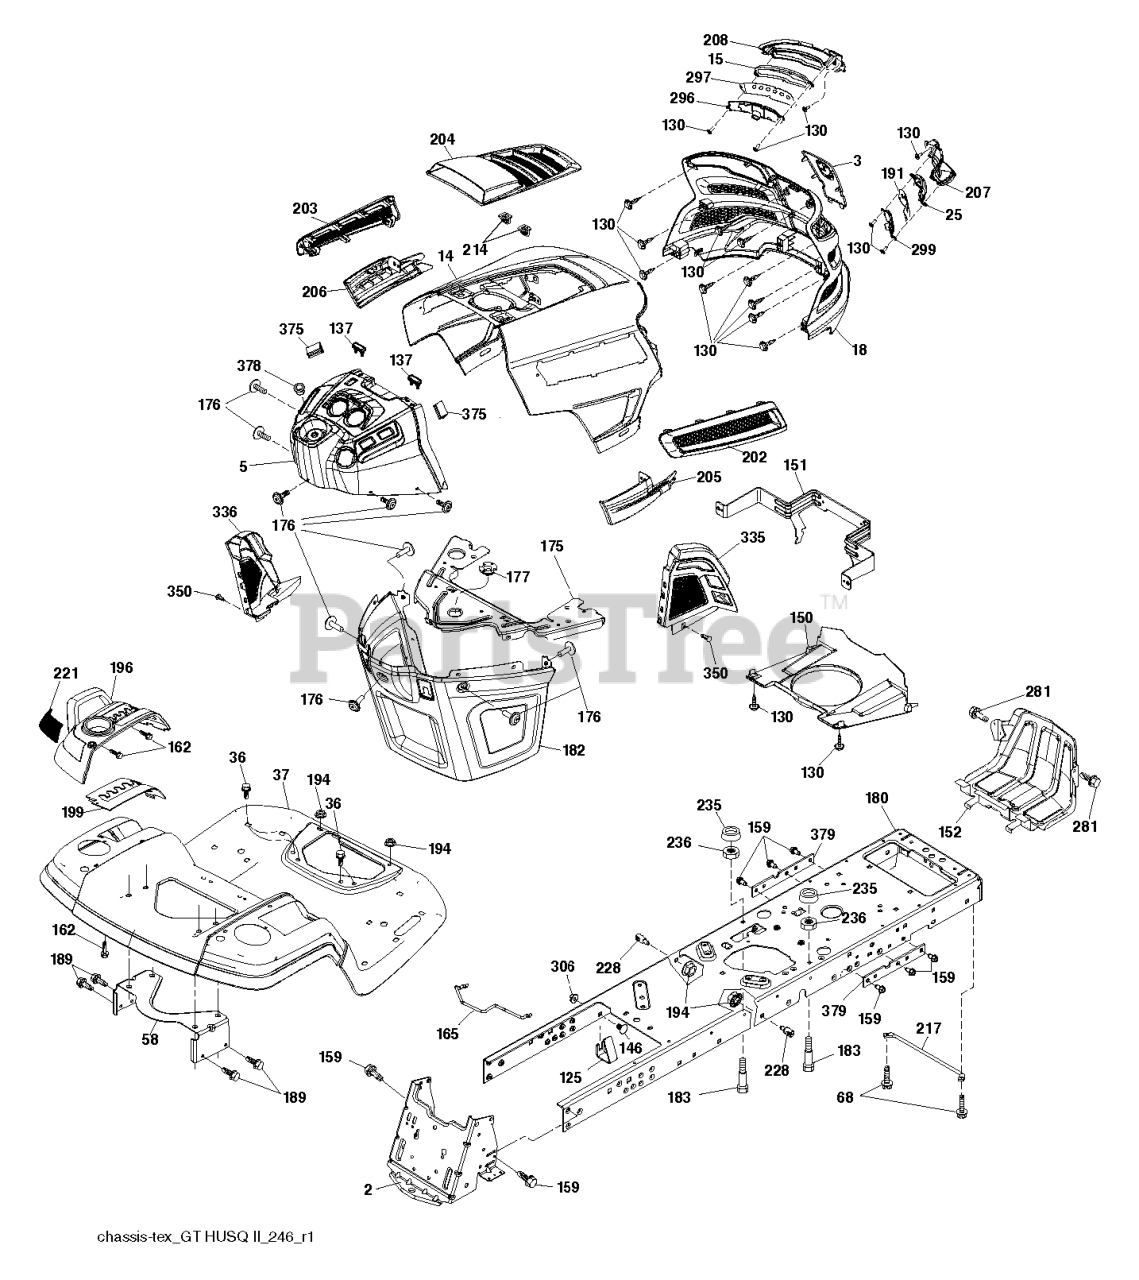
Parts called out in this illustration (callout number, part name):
2	DRAWBAR.STGT
3	APPLIQUE.SUBASM.GT.HUSQ.II
5	DASH.UPR.GT2.DUAL.RD.PT
14	HOOD.ASM.HUSQVARNA.GT.TEX.ORAN
15	LED LIGHT.LH
18	GRILLE SUBASM.GT.II.LOW.HDLGHT
25	LENS.RH
36	SCREW 5/16"
37	FENDER HUSQVARNA GT MS668 - HU
58	BRKT.SUPPORT.FNDR/TANK
68	SCR 5/16-18 X 1/2 SELFTAP ZN
125	CLIP.FUEL.LINE
130	SCREW.#10 X 0.750.BOS
137	BUMPER DASH
146	BOLT.RDHD.SHT.SQNK.3/8-16X5/8
150	AIR.DUCT.GTV.BLACK
151	BRACKET.PIVOT.HOOD.GT.HUSQ.II
152	SHIELD.BROWNING.PNT.GT.V2
159	SCREW, 3/8-16X3/4
162	SCREW.HI-LO.CONSOLE
165	SUPPORT.TANK.REAR.B/TE
175	PLATE.PNT.CROSSMEMBER.HUSQ/PRE
176	SCREW.#10-24X5/8.RN.QU
177	BUSHING STEERING
180	CHASSIS.LT/GT.BOLTED
182	DASH.LOWER.COMMON.12V.ADAPTOR
183	BOLT.5/16-18X1-1/4 FULL THD
189	SCREW
191	INSERT INFLECT.RH
194	NUT LOCK HEX FLANGE 5/16-18
196	CONSOLE.ASM.DECKLIFT.HUSQGT.DL
199	PLATE.DECK.LIFT.HUSQVARNA.GT
202	VENT.SIDE.RH.GT.HUSQ.II.
203	VENT.SIDE.LH.GT.HUSQ.II.498
204	VENT.TOP.HUSQ.GT2
205	SIDE.TRIM.RH.GT.HUSQ.II
206	SIDE.TRIM.LH.GT.HUSQ.II.GRAY
207	BEZEL GT2 LED RH W/ LOWER.ATT
208	BEZEL GT2 LED LH W/ LOWER ATT
214	CLIP.RETAINER.TINNER.
217	ROD.PIVOT.HOOD
221	REFLECTOR.LH.TEX GT HU
228	STUD.FASTNER.W/ANTI-ROTATE
235	SPACER FENDER
236	NUT.CENTERLOCK.5/16-
281	SCREW 3/8-16X1
296	LED LIGHT.LH
297	INSERT REFECT LH
299	LED LIGHT.RH
306	NUT LOCK FLG 3/8-16 UNC
335	COVER.LOWER.DASH.RH.BLACK
336	COVER-LH.LOWER.DASH.GT2.BLACK
350	KIT GUARD BRUSH
375	BUMPER CLIP-ON. DASH 1"
378	BUSHING FLANGE; PLASTIC
379	CHASSIS.PLATE.REINFORCEMNT.431
